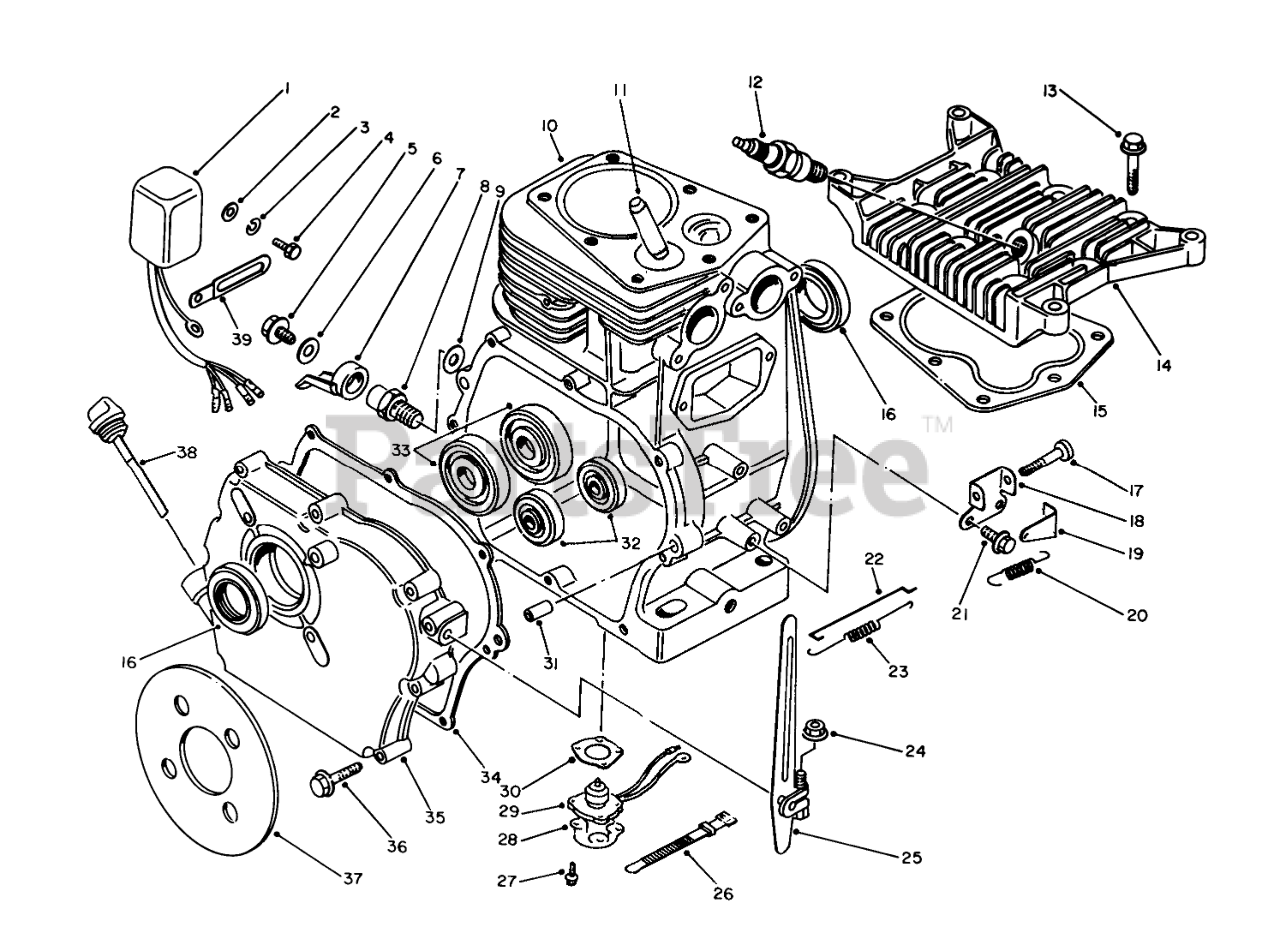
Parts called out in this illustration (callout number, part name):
1	OIL LEVEL UNIT
2	Washer
3	Lockwasher
5	Drain Plug
6	Gasket
7	Plate
8	Adapter
9	GASKET
10	Cylinder
11	VALVE GUIDE
12	SPARK PLUG
14	Cylinder Head
15	Gasket
16	OIL SEAL
18	Bracket
20	SPRING
22	Rod
23	SPRING
24	M6 X 1 LOCKNUT
25	Control Lever
26	Clamp
28	Plate
29	Sensor
30	GASKET
32	Bearing
33	Screw
34	Gasket
35	Cover
38	Gasket
39	Clamp
